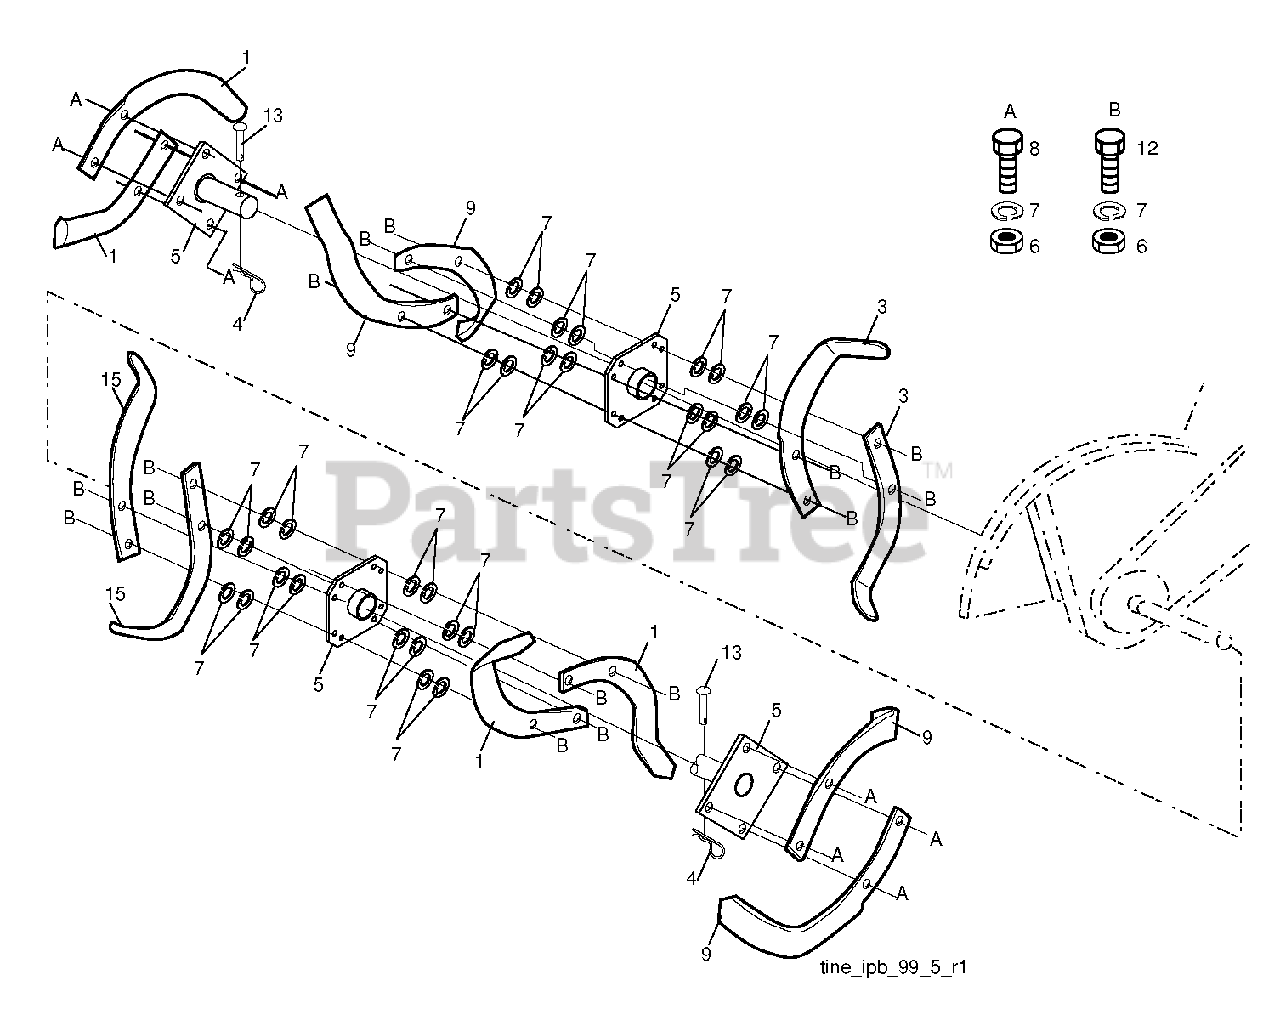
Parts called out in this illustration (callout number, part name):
1	TINE, LH 14"
3	TINE.LH.14".CRT
4	SPRING RETAINER
5	TINE.HUB.ASM.W/SHEILD
6	NUT
7	WASHER, LOCK 3/8
8	BOLT.HEX.001X20.37-24X1.ZINC
9	TINE, RH 14"
12	BOLT.3/8-24X1-1/2
15	TINE.RH.14".CRT
